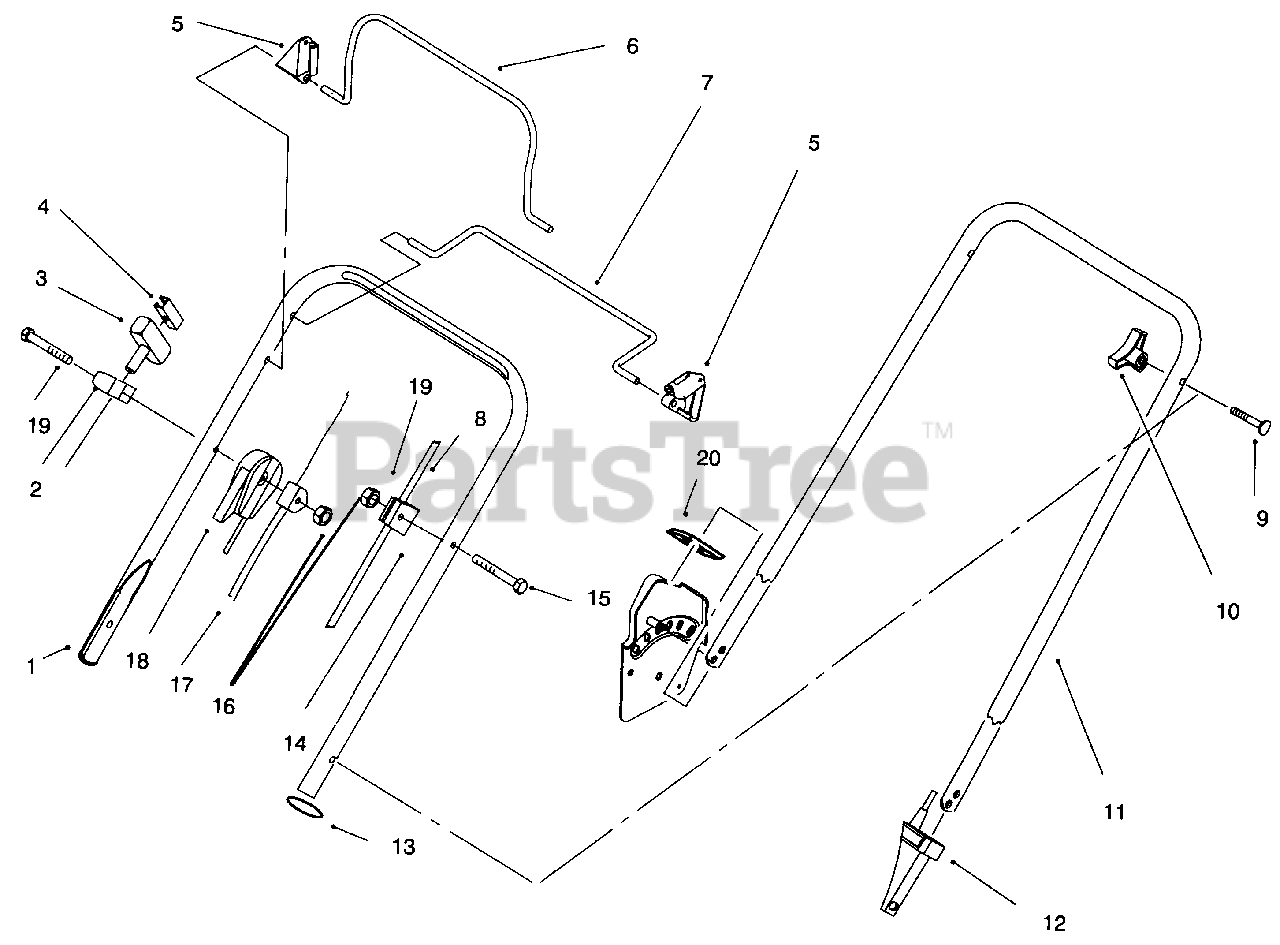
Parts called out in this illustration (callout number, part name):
1	Handle-Upper
2	Guide-Rope
3	Handle-Starter
4	Clip-Rope Insert
5	Stop-Pivot
6	Bail-Brake
7	Bail-Control (Model No. 10302 & 10310 Only)
8	Cable-Traction
9	Screw-Handle
10	Knob-Handle
11	Handle-Lower
12	Anchor-Cable, (Lower) (Model No. 10302 & 10310 Only)
13	Tie Strap
14	Anchor-Cable, (Upper) (Model No. 10302 & 10310 Only)
17	Cable-Brake
18	Cable-Throttle
20	Handle-Guard
